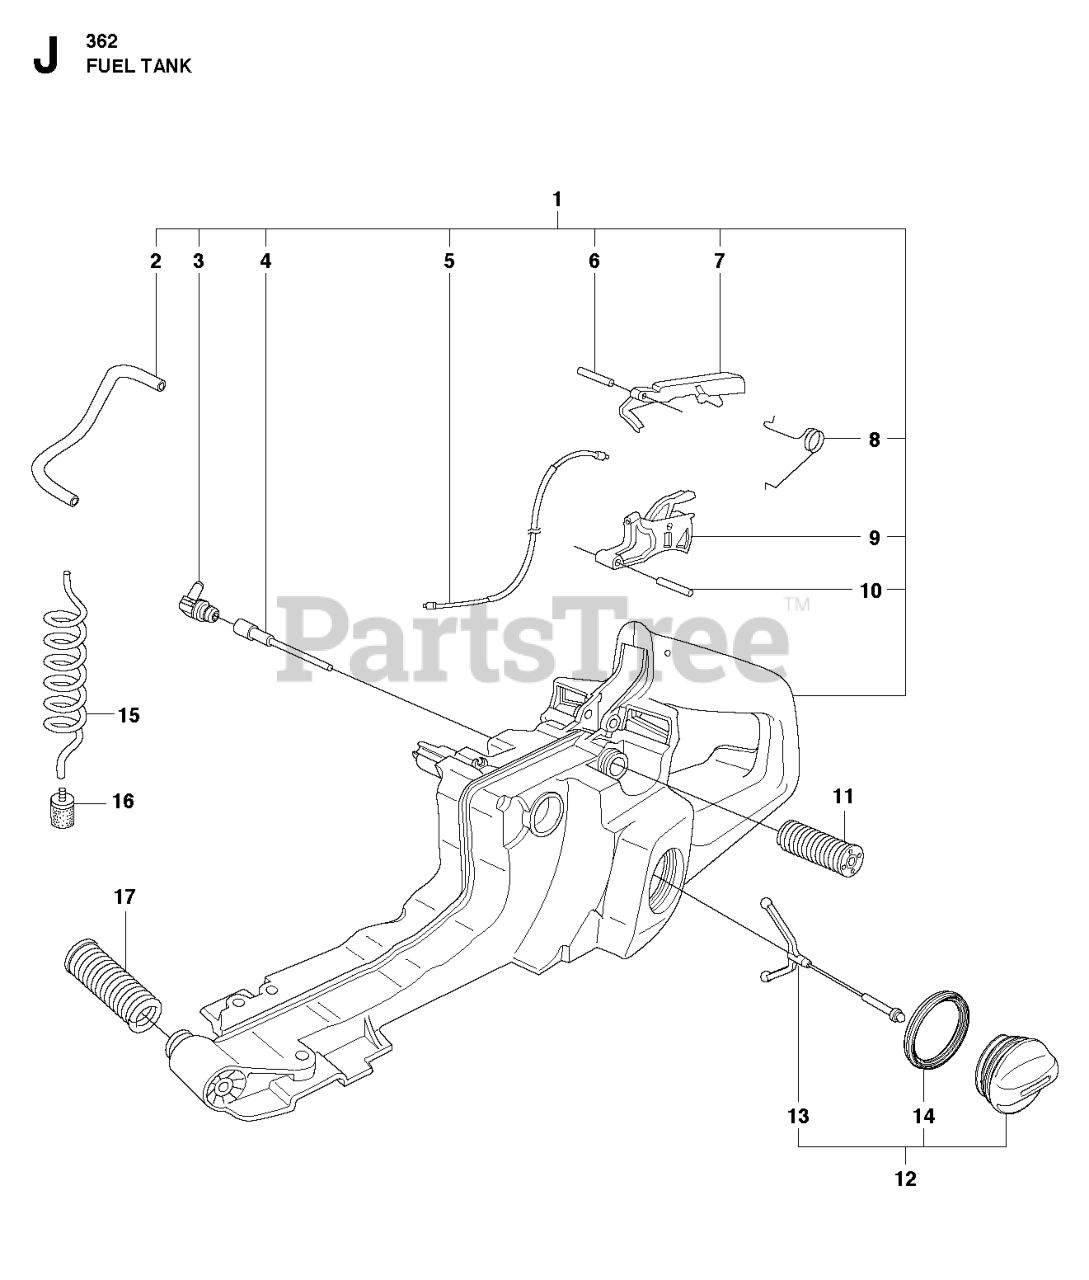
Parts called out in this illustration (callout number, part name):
1	TANK/HANDLE ASSY
2	HOSE
3	CONNECTOR
4	TANK VALVE
5	WIRE
6	PIN 3X25
7	THROTTLE CATCH
8	SPRING
9	THROTTLE TRIGGER
10	PIN CPH8 4X20
11	ANTIVIBE MOUNT
12	TANK CAP
13	TANK LOCK
14	SEALING
15	FUEL HOSE
16	RP FUEL FILTER
17	ANTIVIBE MOUNT
17	AV SPRING (HARD)
